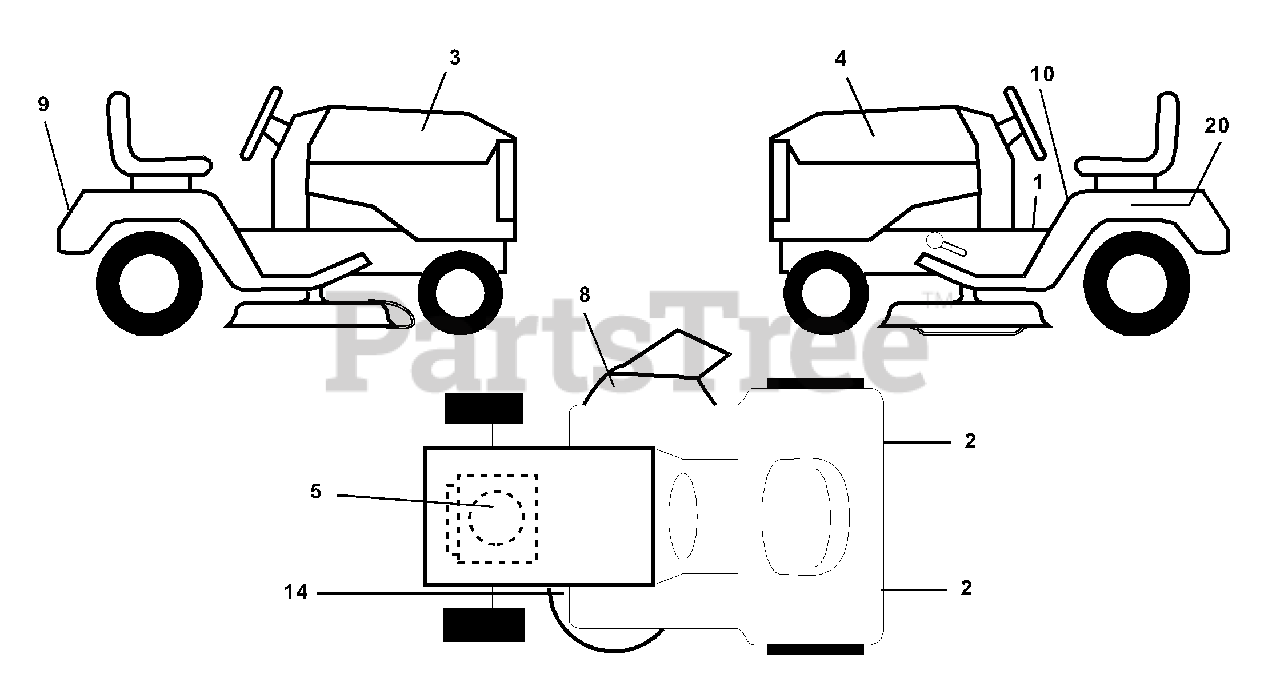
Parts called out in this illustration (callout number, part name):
1	Decal Oper. Step Thru Eng/Fr
2	Reflector Tail Light Red/Amber
3	Decal Hood RH
4	Decal Hood LH
5	Decal HP Engine
8	Decal Warning
9	Decal Fender Husq
10	Decal Fender Danger Eng/Fr
14	Decal V-Belt Schematic
20	Decal Bat Dan/Psn
